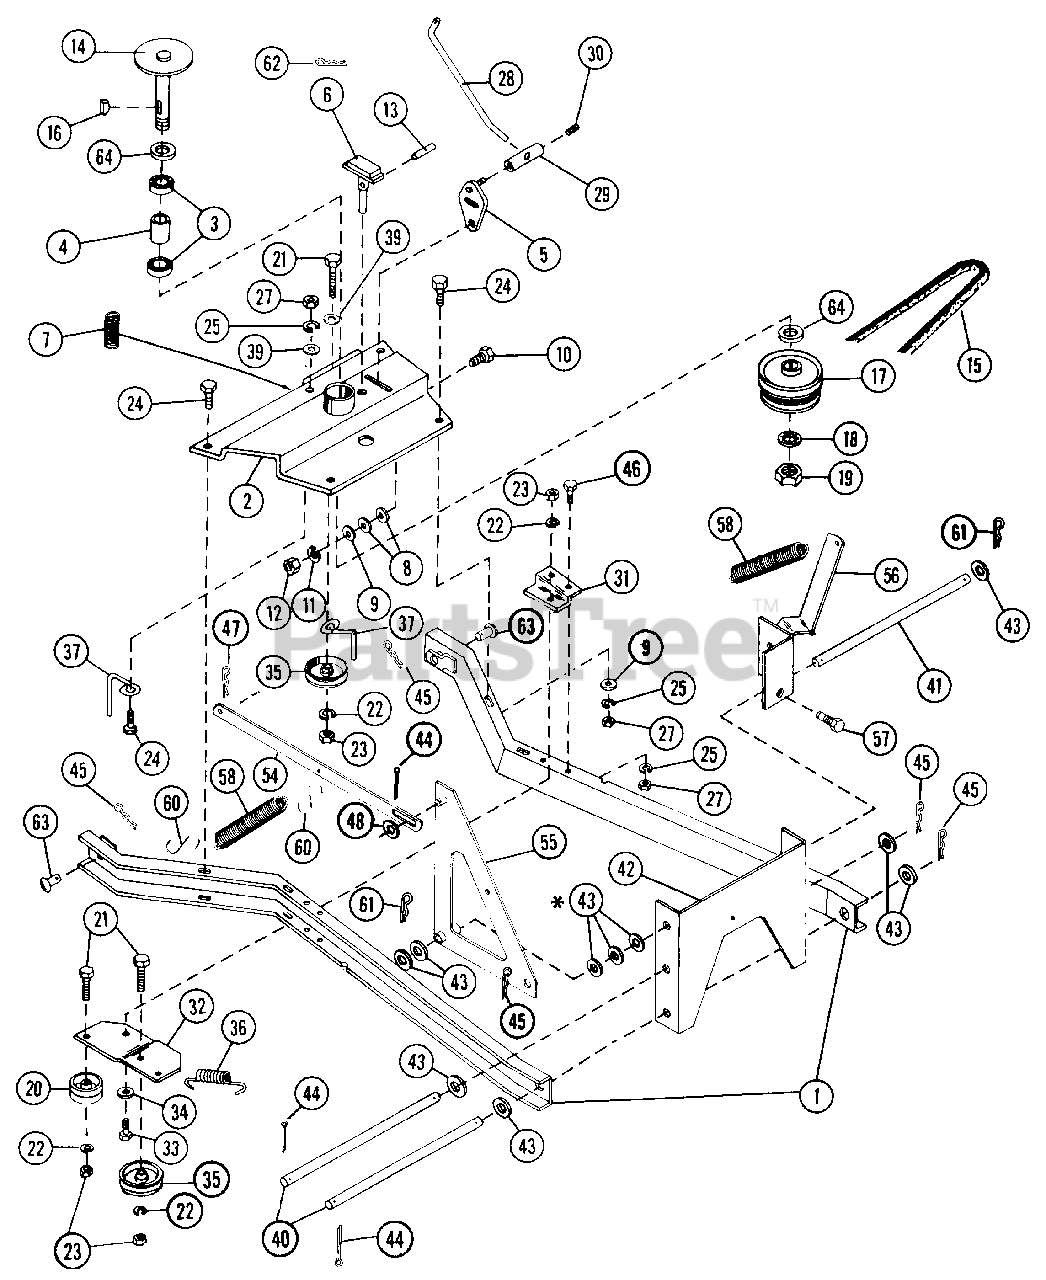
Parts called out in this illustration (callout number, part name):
1	CHANNEL
2	SPINDLE HOUSING
3	RADIAL BEARING
4	SPACER
5	BRAKE ACTUATOR
6	BRAKE PLUNGER
7	SPRING, COMP.
8	WASHER, FLAT .250X.500X.049
9	WASHER, .312X.734X.065
10	BOLT, HEX 1/4-20X.750
11	WASHER, LOCK
12	NUT, HEX 1/4-20
13	PIN, SPRING .187X1.75
14	SPINDLE SHAFT
15	V-BELT
16	KEY, WOODRUFF .187X.75X#9
17	DOUBLE SHEAVE
18	LOCKWASHER, INTERNAL 3/4
19	NUT, JAM 3/4-10 HEX
20	IDLER, .375X2.25
21	BOLT, HEX 3/8-16X1.75
22	WASHER, LOCK 3/8 REG.
23	NUT, HEX 3/8-16
24	BOLT, HEX 5/16-18X1.00
25	WASHER, LOCK 3/8
27	NUT, HEX 5/16-18
28	BRAKE ROD
29	ROD ADAPTOR
30	SET SCREW, 5/16-18X.375 HSCP
31	IDLER MOUNT
32	IDLER ARM
33	SHOULDER BOLT
34	WASHER, FLAT .515X1.441X.1
35	IDLER, .375X3.06
36	SPRING, EXTENSION 3-1/16 FREE LER
37	BELT FINGER
39	WASHER, .406X.875X.083
40	PIVOT ROD
41	SHAFT, SNOWBLOWER MOUNTING
42	PIVOT SUPPORT
43	WASHER, .656X1.312X.095
44	PIN, COTTER 5/32X1.50
45	PIN, HAIR INT. 3/32X1-7/8
46	BOLT, HEX 5/16-18X.75
47	HAIR PIN, INTERNAL
48	WASHER, FLAT .500X1.250X.083
54	LIFT STRAP
55	LIFT BELLCRANK
56	SPRING ANCHOR
57	BOLT, HEX 1/2-13X1.25
58	SPRING, EXTENSION 9-15/16 FREE LE
60	S HOOK
61	PIN, HAIR .141X2.75
62	PIN, HAIR INT. 3/32
63	PIN, CLEVIS
64	WASHER, FLAT .813X2.0X.148
65	BUSHING, .750X1.002X.625
